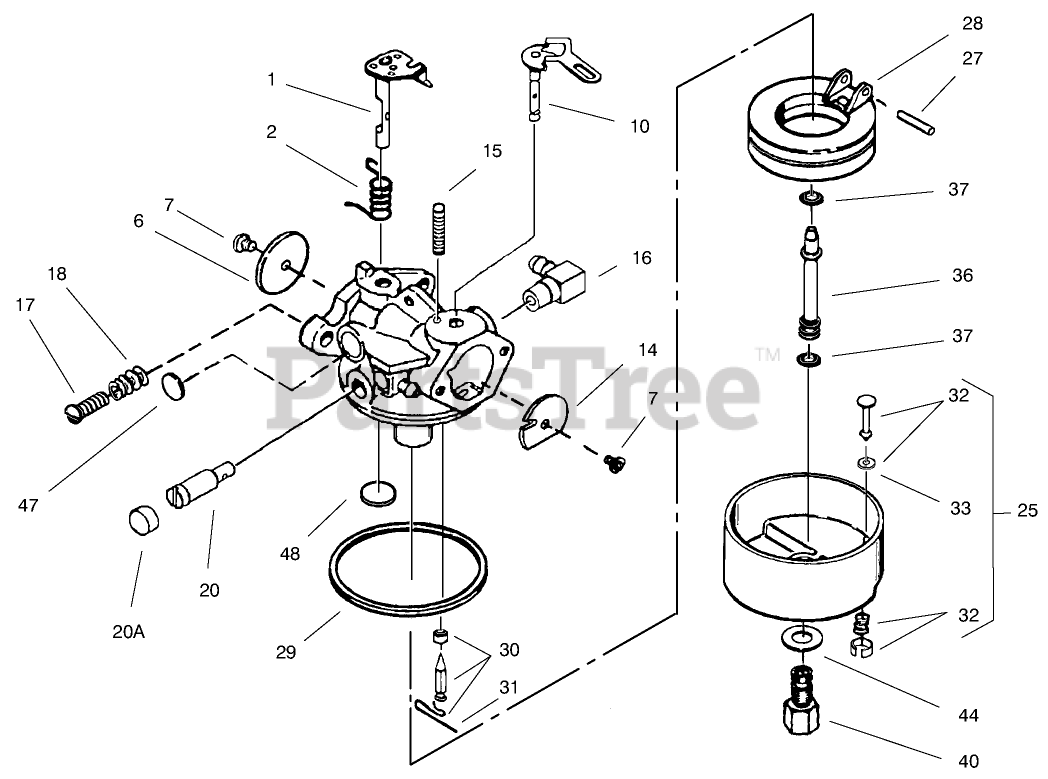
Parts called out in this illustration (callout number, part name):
1	Throttle Shaft and Lever ASM
2	Spring-Return, Throttle
6	Shutter-Throttle
7	Screw-Shutter
10	Choke Shaft and Lever Asm
14	Shutter-Choke
15	Spring-Positioning, Choke
16	Fitting-Fuel
17	Screw-Throttle Crack and Idle Speed
18	Spring-Tension
20	Screw-Restrictor, Idle
20A	Cap-Screw, Idle Restrictor
25	Float Bowl Asm. (Incl. Ref. # 32, 33)
27	Shaft-Float
28	Float
29	O Ring-Bowl, Float
30	Inlet Needle, Seat Clip Assy. (Incl. No. 13)
31	Clip-Spring
32	Bowl Drain ASM
33	Gasket-Plunger, Drain
36	Tube-Nozzle, Main
37	O-Ring
40	Nut-Bowl, High Speed
44	Washer-Bowl Nut
47	Plug-Welch, Idle Mixture Well
48	Plug-Welch, Atmospheric Vent
